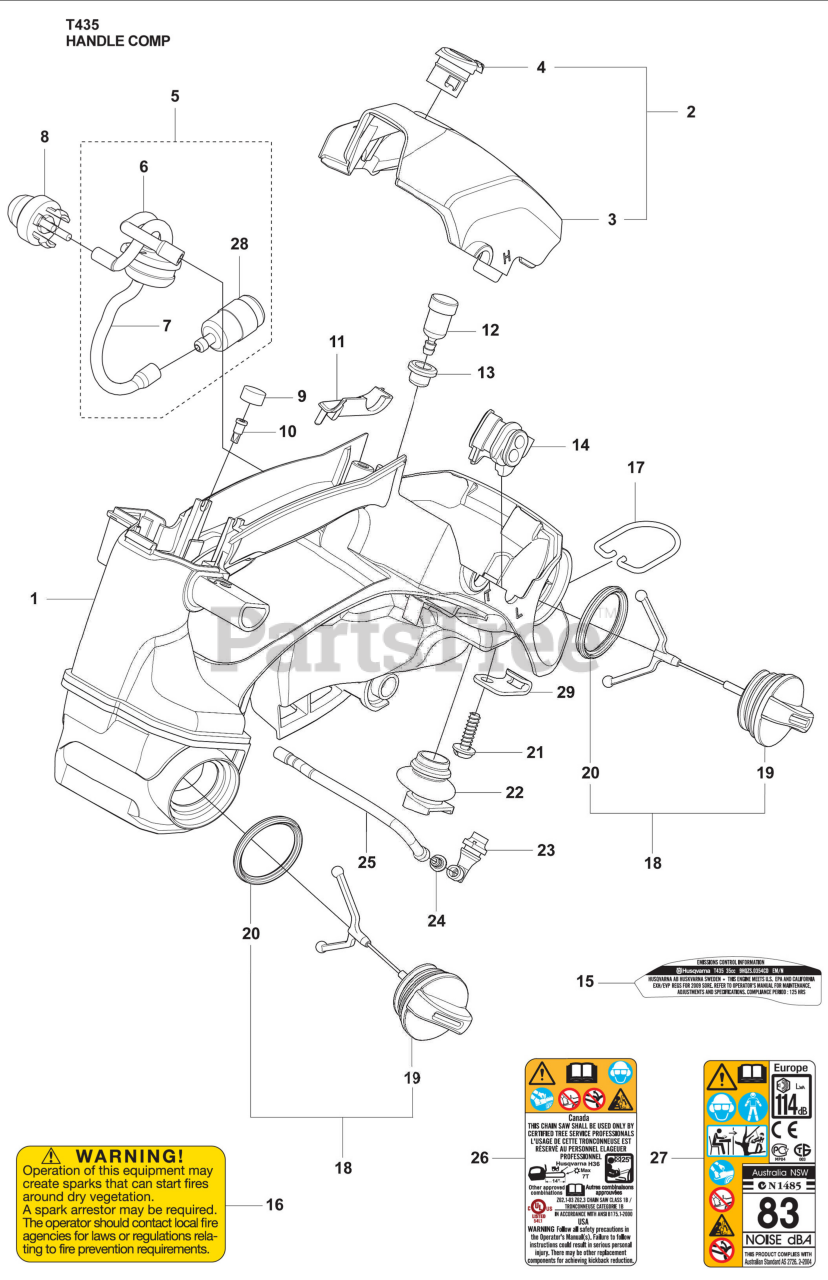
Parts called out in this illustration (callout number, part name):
1	Housing
2	Filter cover compl.
3	Filter cover
5	Fuel hose assy
6	Grommet
7	Fuel hose
8	Purge
9	Seal
12	Breather
13	Grommet
14	Guide, carb
15	Decal, ECI
16	Decal, warning
18	Fuel cap compl.
19	Fuel cap
20	Seal
23	Hose connector
25	Hose
26	Decal, warning US-CAN
27	Decal, warning EU-ROW
28	Fuel filter
